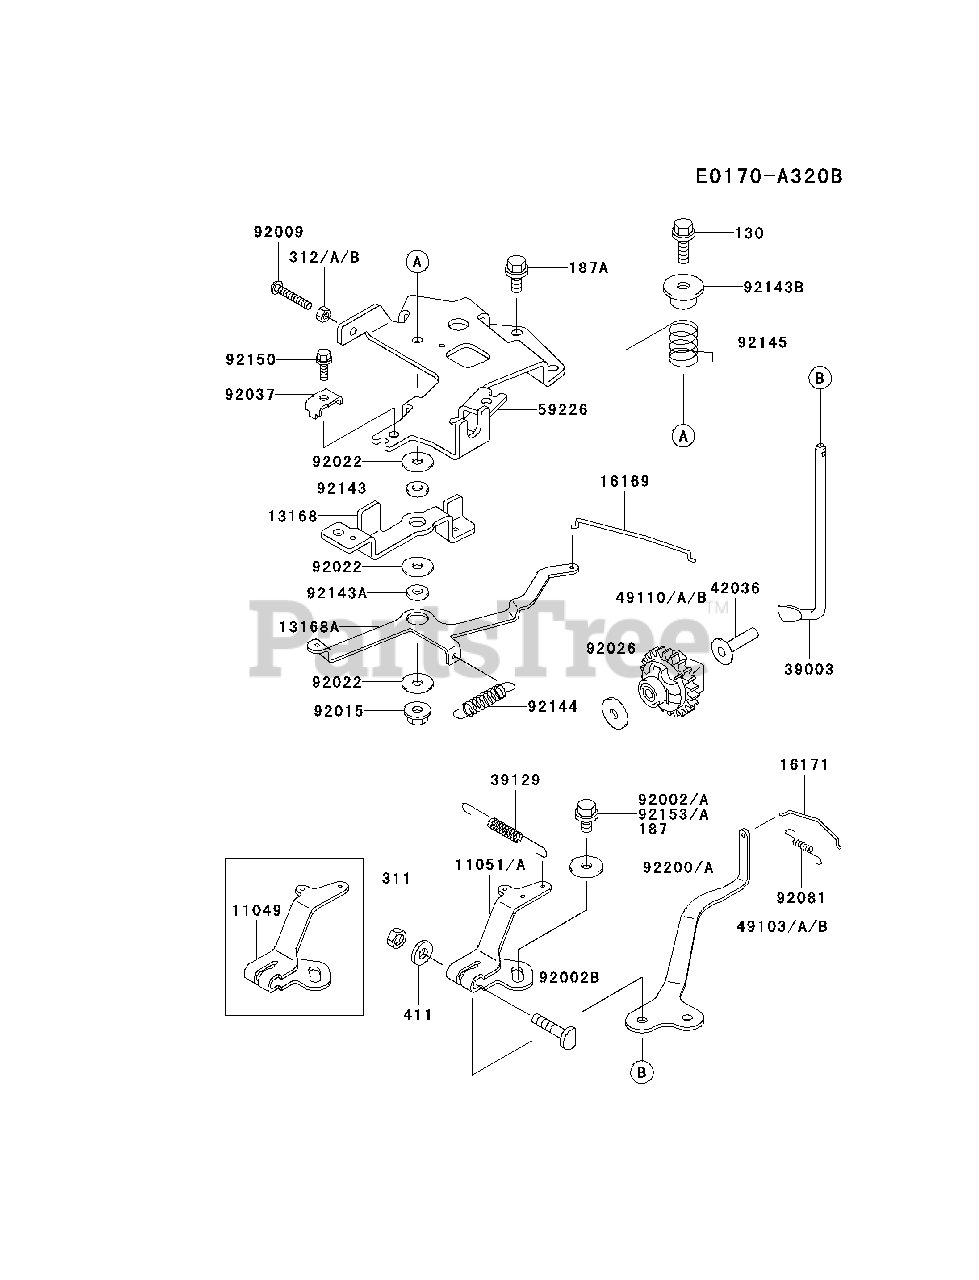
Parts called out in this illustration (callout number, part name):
130	BOLT-FLANGED
187	BOLT-UPSET-WSP
187A	BOLT-UPSET-WSP
311	NUT-HEX
312A	NUT-HEX
312B	NUT-HEX
411	WASHER-PLAIN
